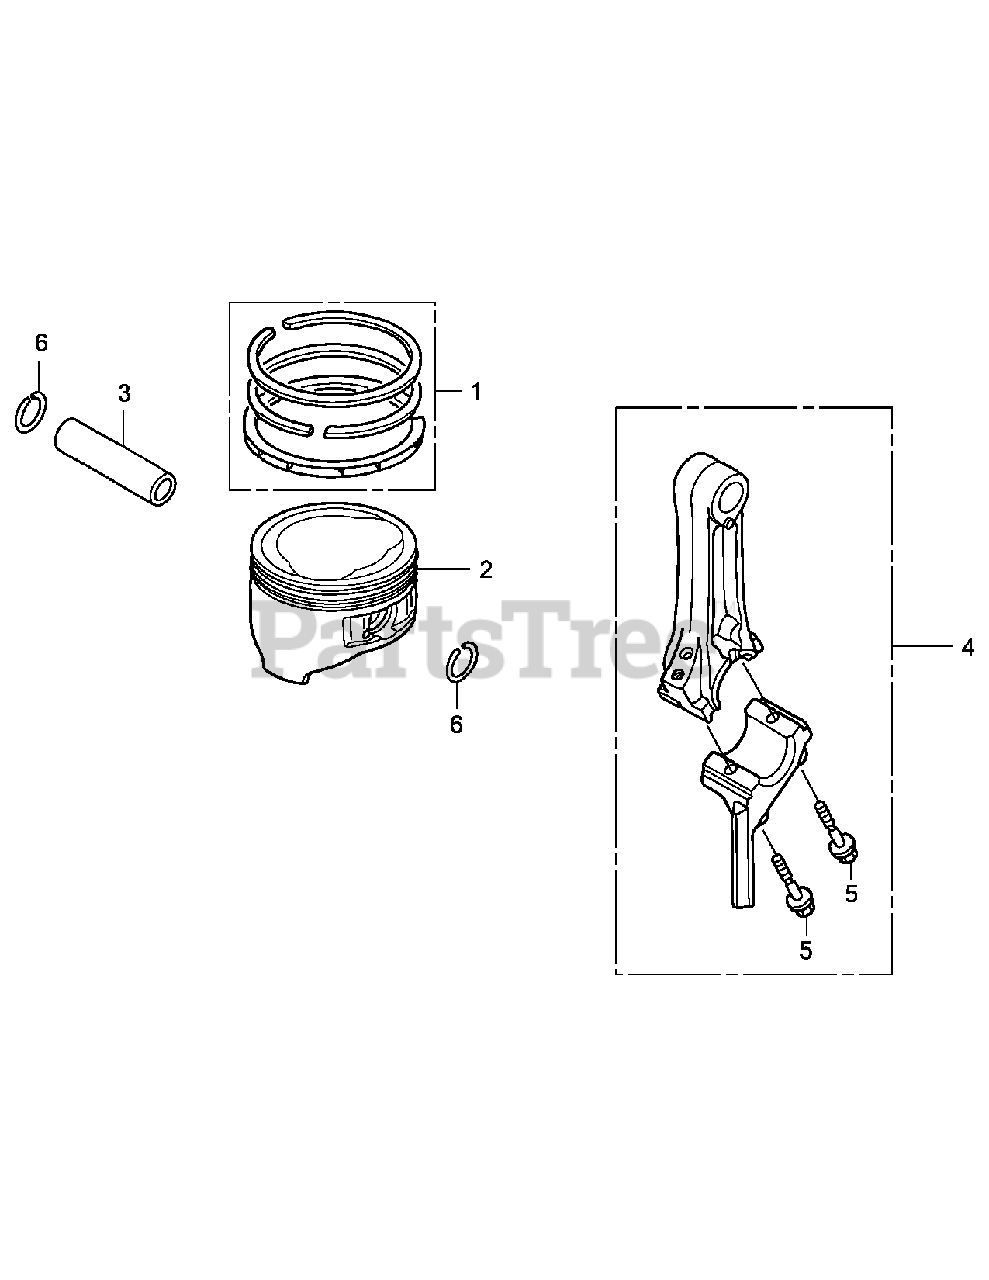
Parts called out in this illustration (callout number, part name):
1	Ring Set, Piston (Std)
2	Piston
3	Pin, Piston
4	Rod Assembly, Connecting
5	Bolt, Connecting Rod
6	Clip, Piston Pin 13mm
